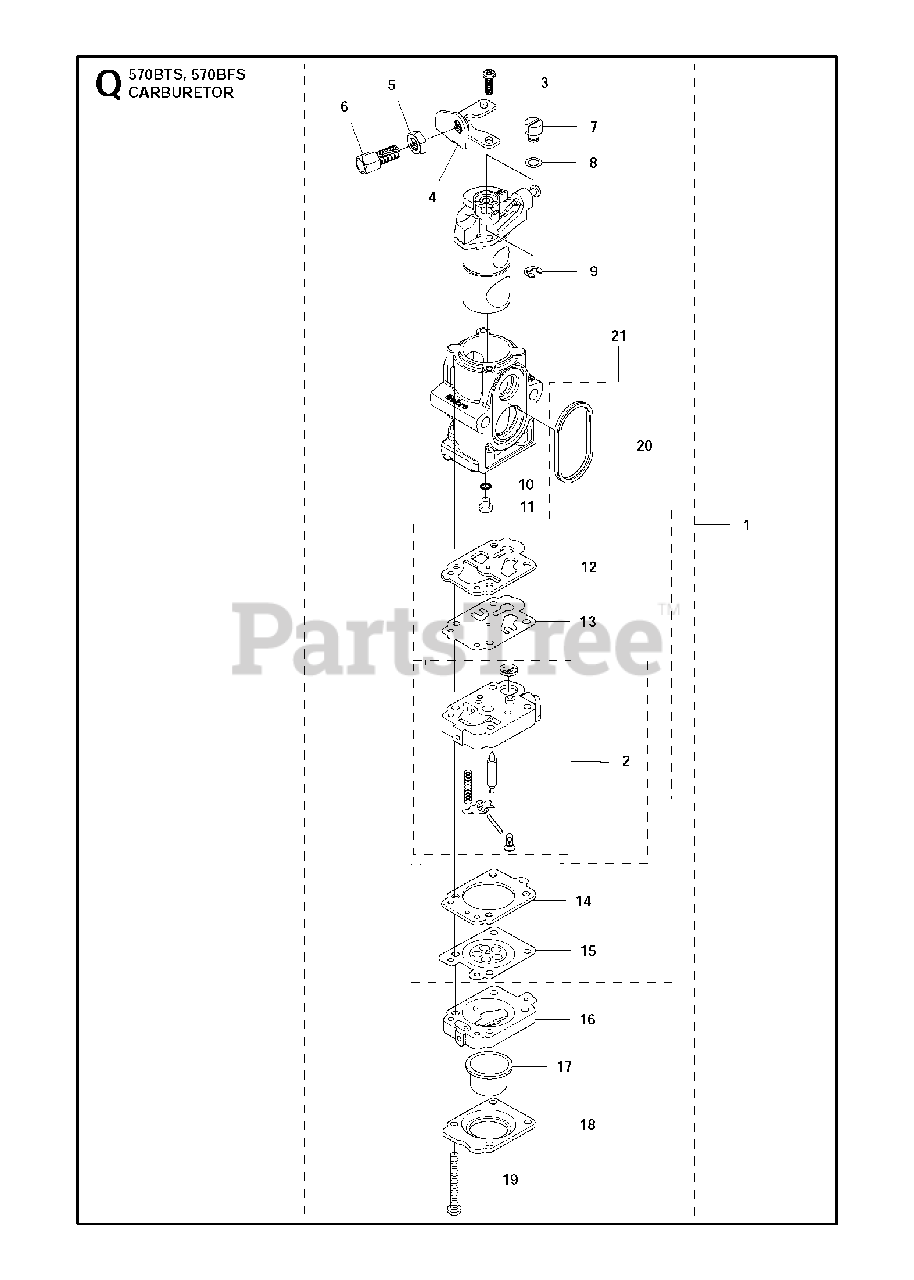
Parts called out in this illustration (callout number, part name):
1	CARB
2	BODY-A-PUMP
3	SCREW
4	BRACKET
5	NUT
6	ADJUSTER
7	SWIVEL
8	WASHER
9	RING
10	O-RING
11	JET #58
12	GASKET
13	DIAPHRAGM
14	GASKET
15	DIAPHRAGM
16	BODY
17	PUMP
18	1OVER
19	SCREW
20	RING
21	GASKET KIT
